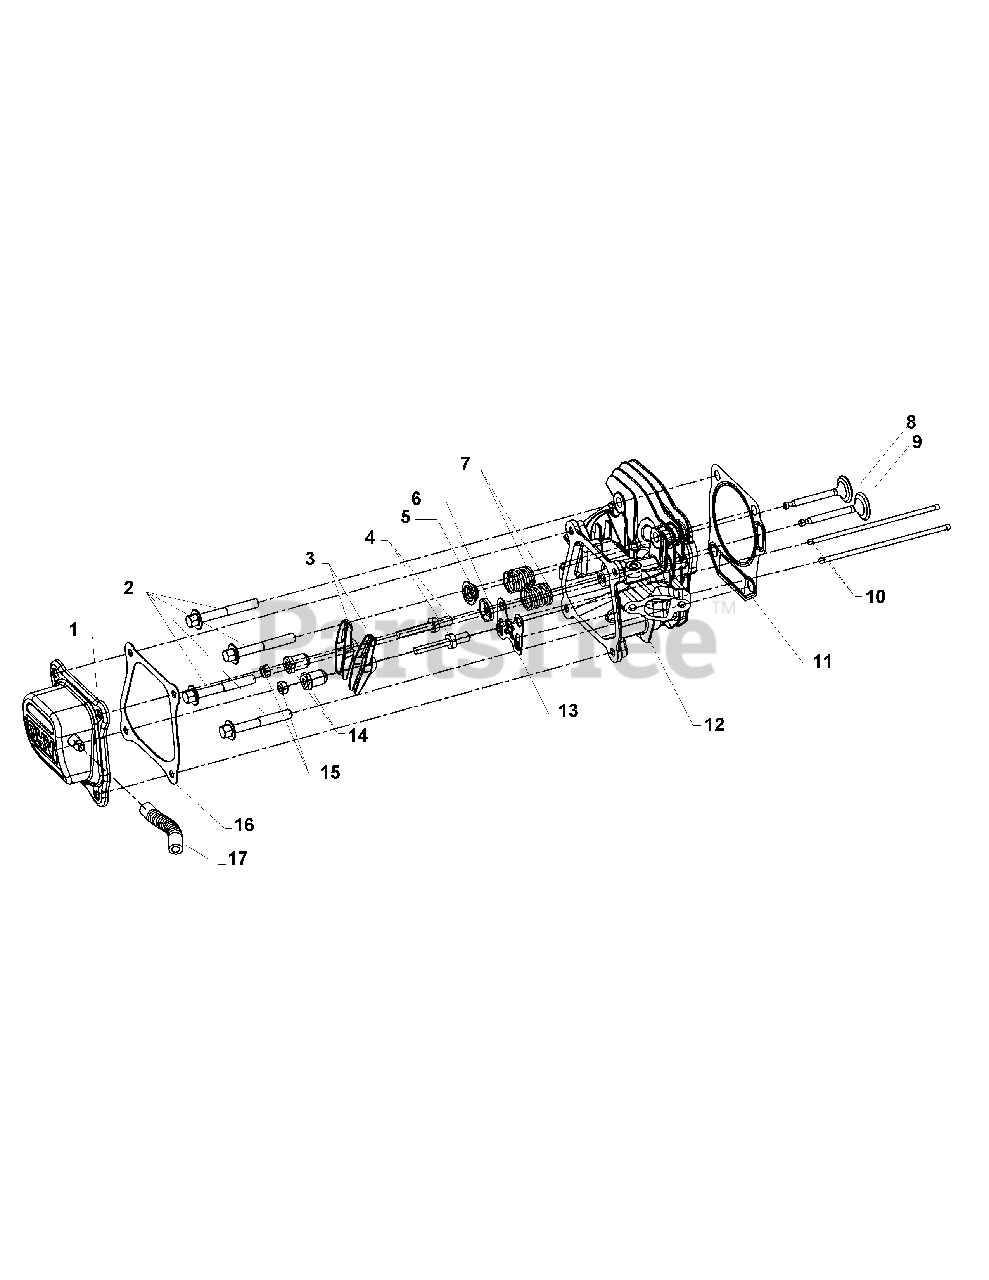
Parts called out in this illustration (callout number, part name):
1	Valve Cover Assembly Kit
4	Rocker Arm Stud
5	Exhaust Valve Spring Retainer
6	Valve Spring Retainer
8	Exhaust Valve
11	Head Gasket Kit
12	Cylinder Head Assembly Kit
13	Pushrod Guide Plate
14	Rocker Arm Pivot
16	Valve Cover Gasket
17	Breather Tube
